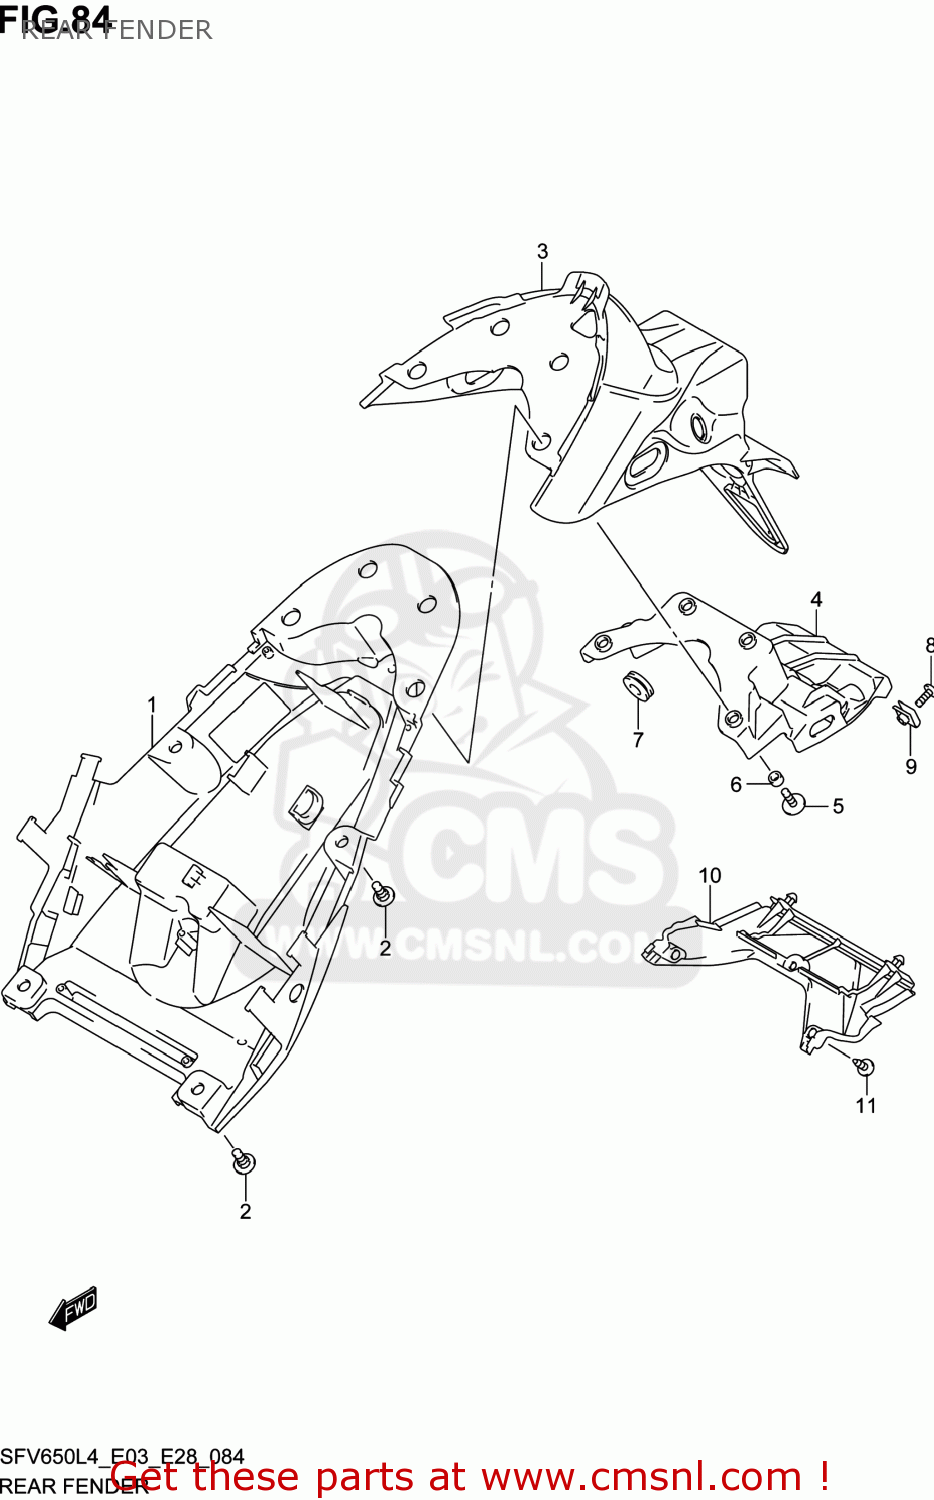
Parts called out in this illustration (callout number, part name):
1	FENDER,RR FR
2	BOLT(6X12)
3	FENDER,RR RR
4	BRACKET,RR FENDER RR
5	BOLT(6X20)
6	SPACER(6.1X9X7.5)
7	CUSHION
8	SCREW
9	NUT
10	COVER,RR FENDER RR
11	SCREW
